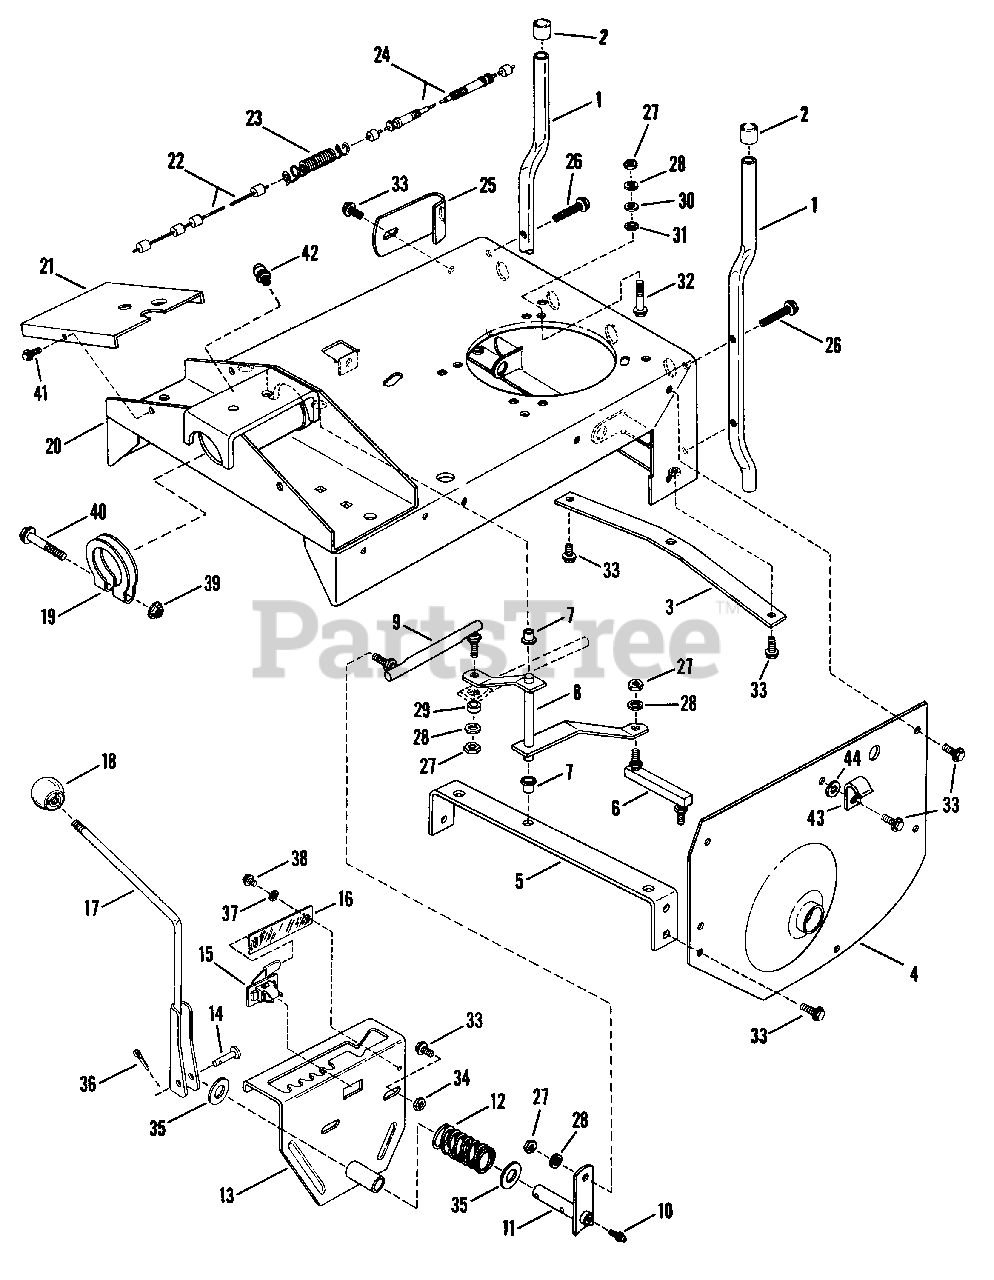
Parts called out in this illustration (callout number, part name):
1	BUMPER, Rear
2	CAP, Bumper
3	PLATE, Hitch
4	FENDER, Left Hand
5	BRACE, Cross
6	LINK, Shift, Short
7	BUSHING, Nylon
8	ARM, Shift
9	LINK, Shift, Long
10	FITTING, Lube (Press fit for .187 hole-no ball)
11	ARM, Shift Handle
12	SPRING, Shift Handle
13	DETENT, Shift
14	CLEVIS-PIN, 3/8x1 1/4"
15	SWITCH, Interlock, Assembly
16	PROTECTOR, Switch
17	HANDLE, Shift
18	KNOB, Shifter Ball
19	CLAMP, Main Tube
20	MAIN CASE
21	PANEL, Switch
22	CABLE, Brake 33 & 41"
23	SPRING, Brake Cable
24	HOUSING, Brake Cable
25	SUPPORT, Bumper
26	SCREW, Self-Tapping, 5/16-18x1 1/2"
27	NUT, 5/16-24 Hex
28	LOCKWASHER, 5/16 Split
29	ROLLER
30	WASHER, 5/16 SAE Flat
31	RETAINER, Bolt
32	SCREW, 5/16-24x1 1/2" Hex Cap
33	SCREW, Self-Tapping, 5/16-18x5/8"
34	NUT, 5/16-18 Hex
35	WASHER, Thrust
36	COTTER-PIN, 3/32 x 3/4"
37	WASHER, #10 SAE
38	SCREW, #10-24 x 1/2" Hex Washer Self-Tap (Torx)
39	LOCKNUT, 5/16-24 Hex Flange
40	SCREW, 5/16-24 x 2 1/2" Hex Cap
41	SCREW, 1/4-28 x 5/8" Self-Tapping
42	FITTING, Lube
43	CLIP, Wiring
44	LOCKWASHER, 5/16 Internal Tooth
